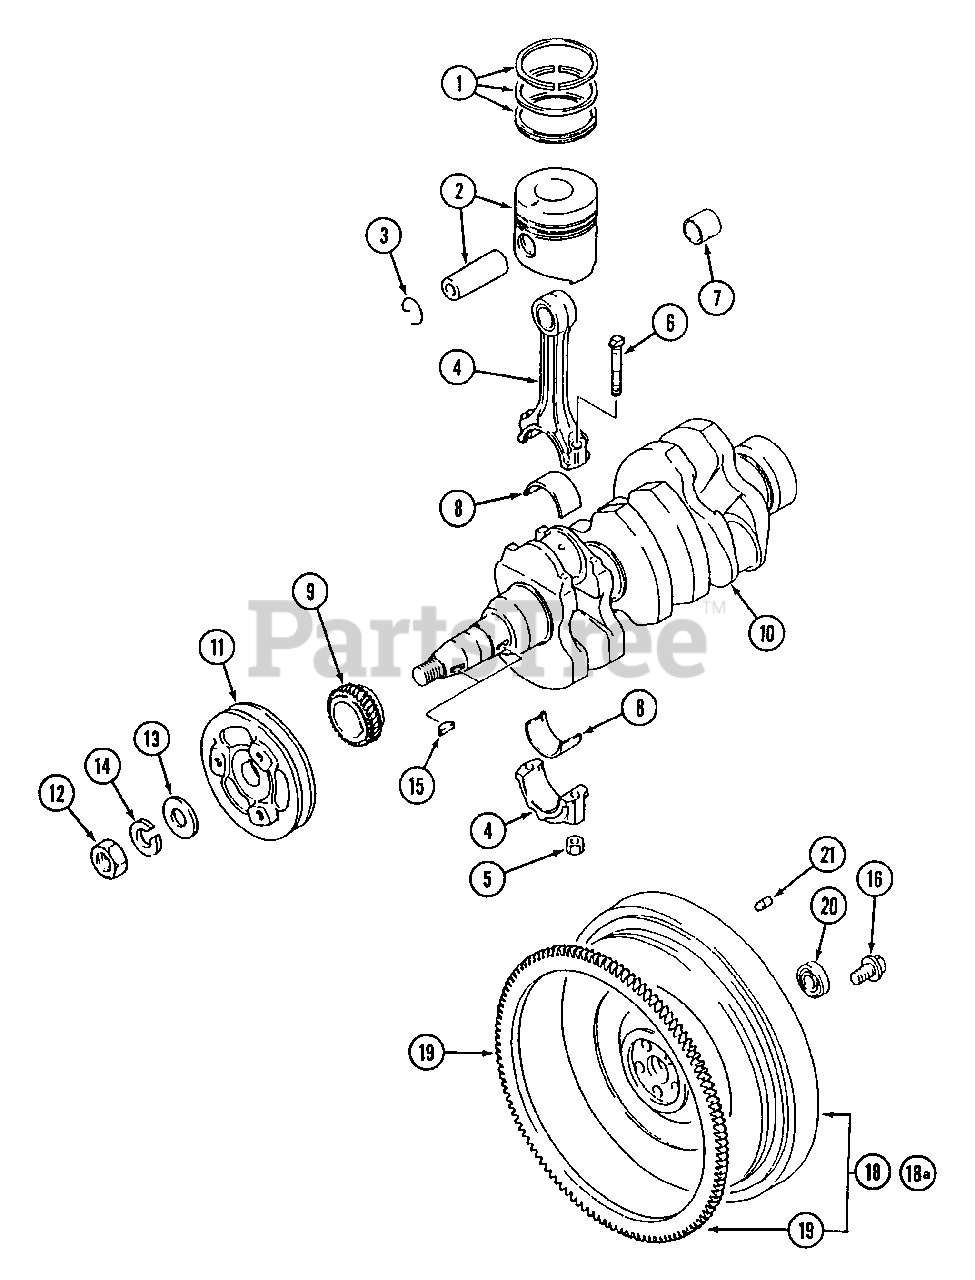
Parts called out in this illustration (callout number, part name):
1	Ring Set, Piston
2	Piston & Piston Pin Set
3	Clip, Piston Pin
4	Con-Rod Ass'y.
5	Nut, Connecting Rod
6	Bolt, Connecting Rod
7	Bearing, Small End
8	Bearing Set, Con-Rod
9	Gear, Crankshaft
10	Crankshaft
11	Pulley, Crankshaft
13	Washer, Plain
14	Washer, Spring
15	Key, Woodruff
16	Bolt, Drive Plate
18	Flywheel Sub Ass'y.
18A	Flywheel Sub Ass'y.
20	Bearing, Ball
21	Pin, Dowel
